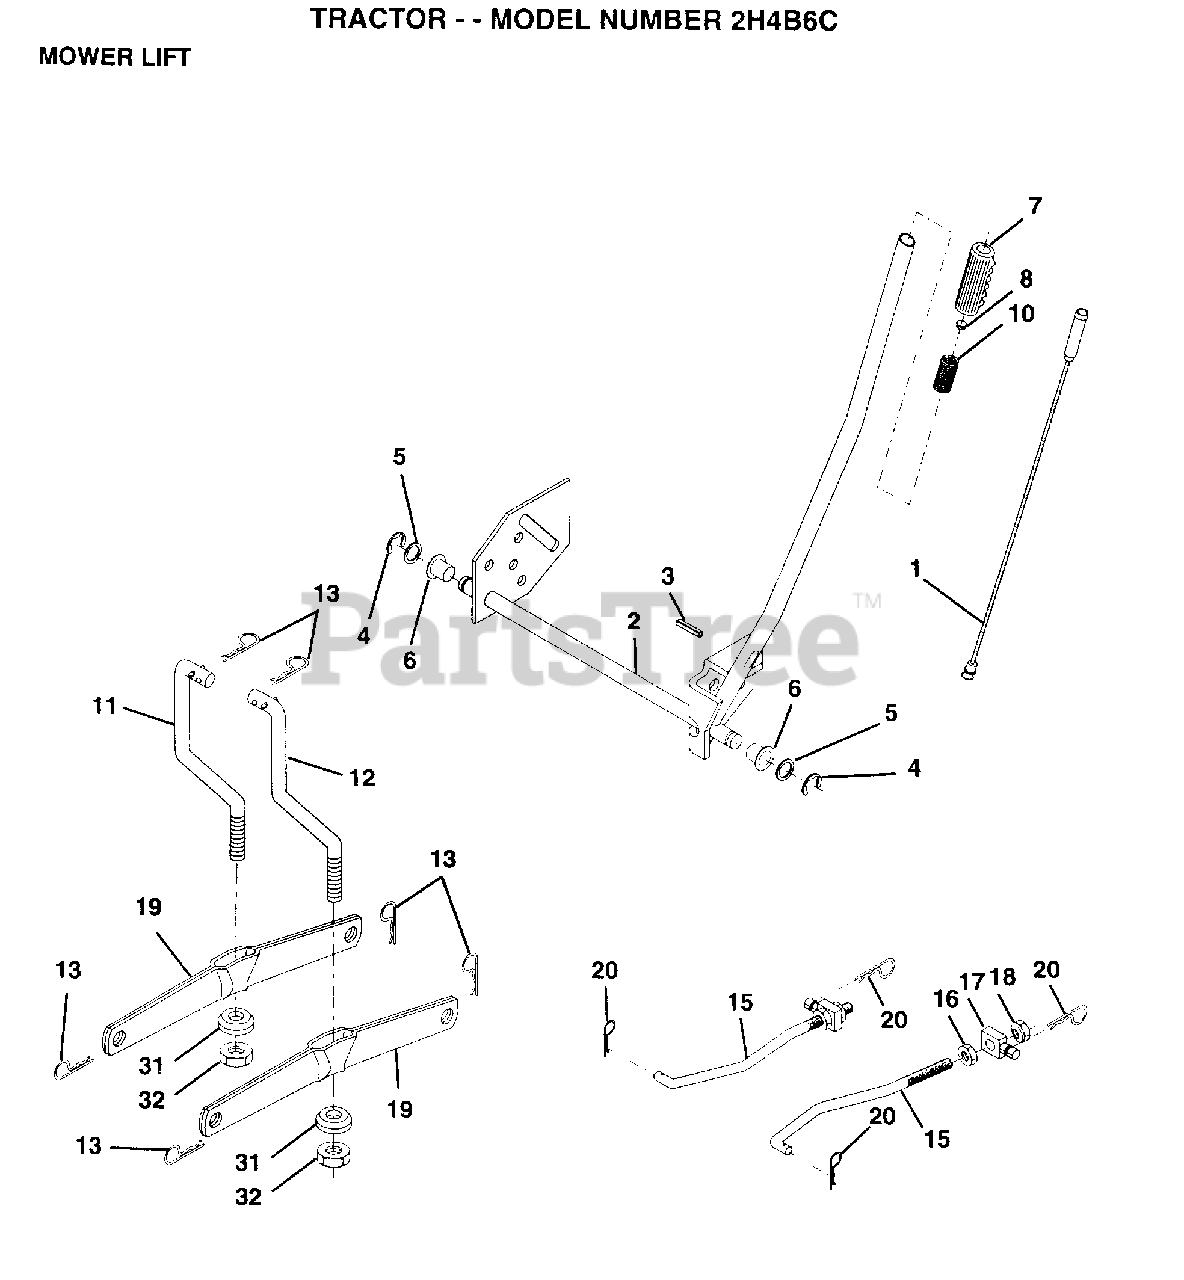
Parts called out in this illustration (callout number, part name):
1	WIRE ASM
3	PIN-GROOVE LT
5	WASHER
6	NYLON BEARING
7	GRIP
15	LINK.FRONT
16	NUT
17	TRUNION
18	NUT.LK.W/WSH.1/2.
19	ARM SUSP REAR
20	RETAINER.SPRING
31	BEARING PVT LH
32	NUT.CROWNLOCK.3/8
